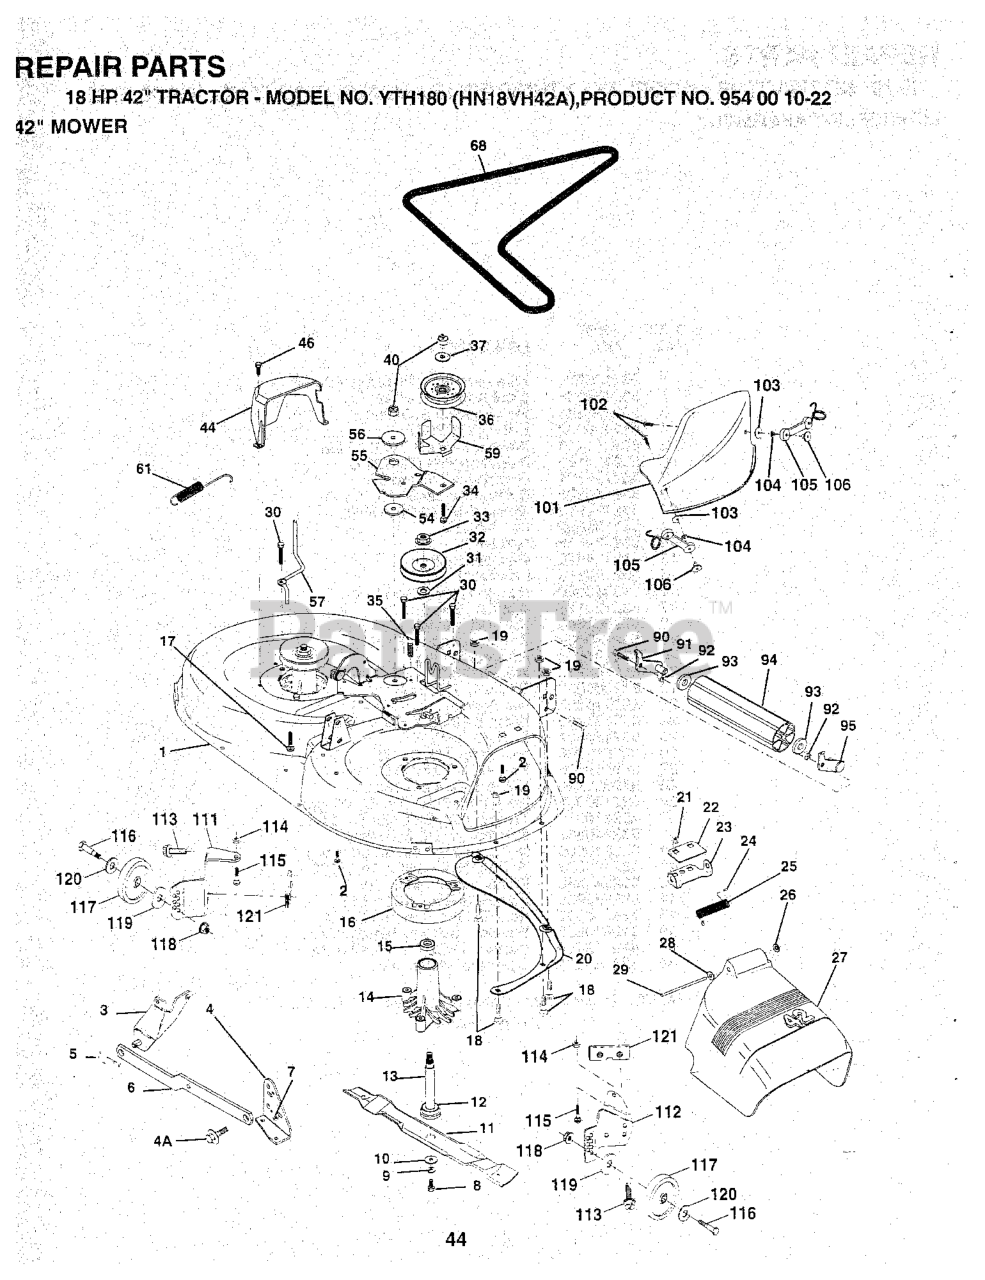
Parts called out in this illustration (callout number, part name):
1	DECK ASM MWR 42"
2	RP BOLT 5/16-18 X3/4 ZN/YEL GR
3	BRKT ASM SWAY BAR
4	BRKT DECK SW BAR
4A	BOLT SHD 5/16-18
5	RETAINER-SPRNG RB
6	REAR SUSP ARM
7	NUT.71038.31-18.HEX.NYLOCK
8	BLADE BOLT
9	LOCKWASHER
10	WASHER.BLADE
11	BLADE.42".MULCH
12	BEARING.BALL.#6204.(MANDREL)
13	SHAFT ASM VENT
14	HOUSING.MANDREL.VENTED (MACHD)
16	STRIPPER
17	BOLT
18	BOLT
19	NUT.71038.31-18.HEX.NYLOCK
20	BAFFLE
21	NUT.71038.31-18.HEX.NYLOCK
22	STIFFENER BRACKET
23	DEFLECTOR BRACKET
24	CAP-SLEEVE LT
25	SPRING TORSION
26	NUT PUSH M
27	SHIELD.DEFLECTOR.MOWER.42".BLK
28	Washer 11/32 x 5/8 x 16 Ga SD
29	ROD.HINGE
30	SCREW
31	WASHER
32	MANDREL PULLEY
33	NUT
35	FASTENER.XMAS.TREE
36	FLAT IDLER PULLEY
37	WASHER
40	NUT
46	SCREW.1/4-20X5/8
55	IDLER ARM
56	SPACER RETAINER
59	GUARD, BELT
61	SPRING EXTENSION
68	RP.V-BELT
90	BOLT
91	BRACKET LH (A)
93	Washer 1 17/32 X 7/8 X 16 Ga
94	NOSE ROLLER
95	BRACKET RH (B)
101	COVER MULCH 42"
102	SCREW
103	LOCKWASHER #10
105	LATCH ASSEMBLY
106	WELDNUT
111	BRACKET
112	BRACKET
113	BOLT
114	NUT
115	BOLT.CARR.5/16-18X1/2
116	FENDER
117	WHEEL.GAUGE.BLK.4.93
118	LOCKNUT
119	WASHER.5/16.FLAT.STE.STD.
120	Washer 17/32 x 15/16 x 12 Gauge
121	DECK SERV MB42
121	KIT.MANDREL.ASM.3.BOLT
